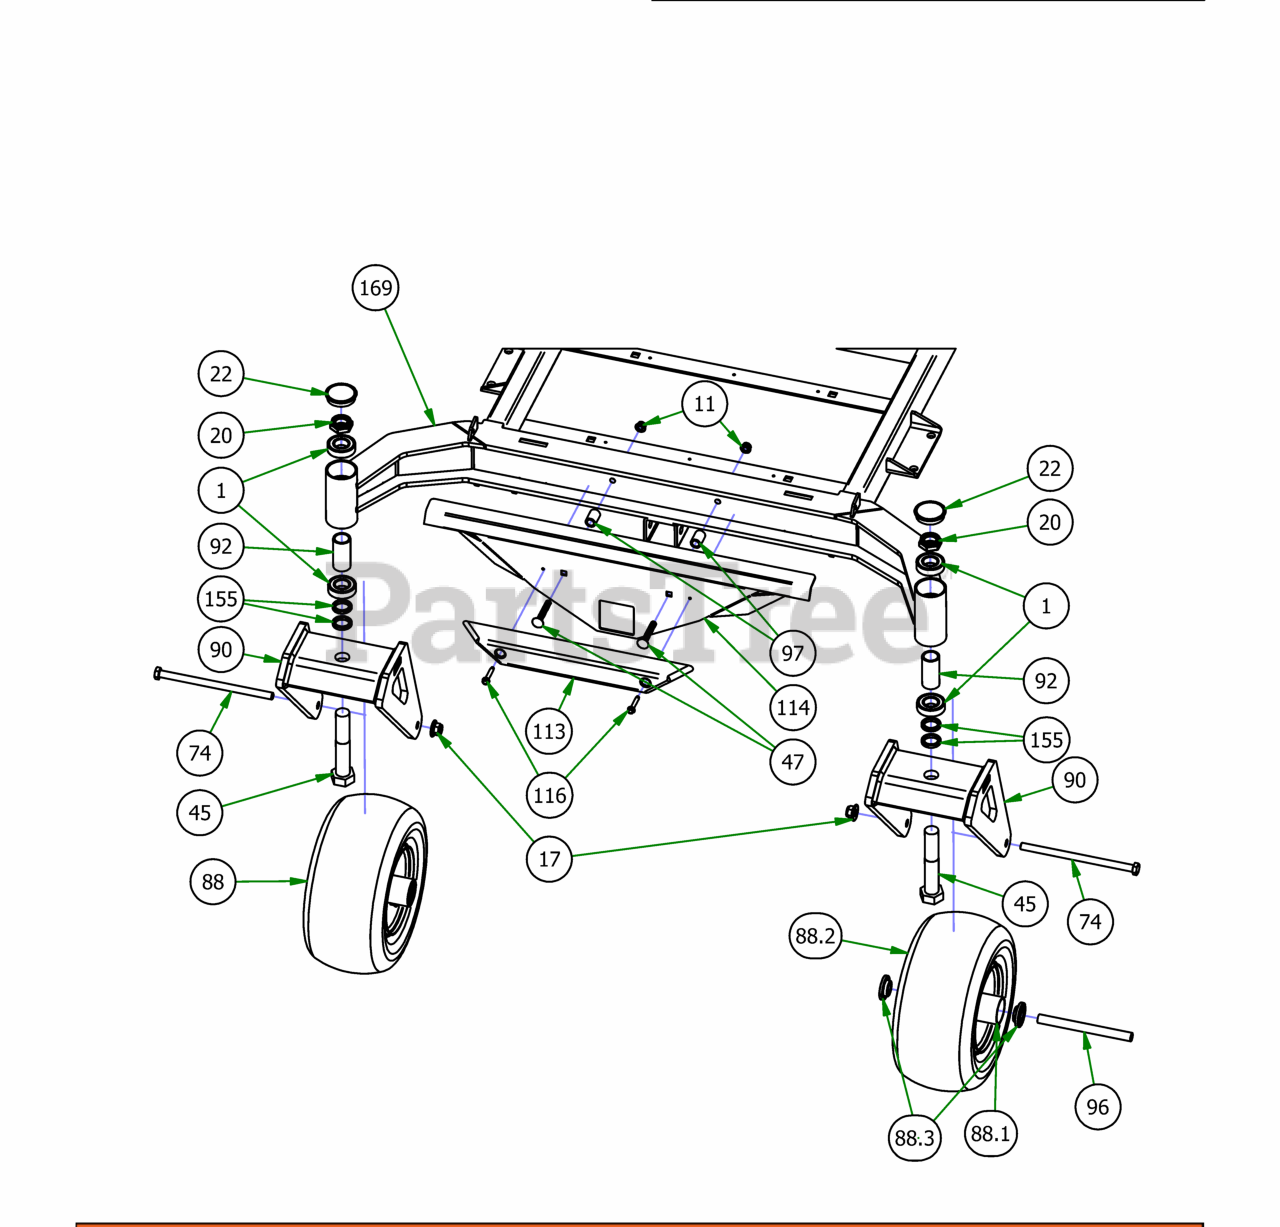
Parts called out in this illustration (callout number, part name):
1	1641 BEARING W/2 CONTACT RUBBER SEALS
11	3/8" Nylock Flange Nut
17	1/2-13 NYLON INSERT FLANGE LOCKNUT ZINC
20	1" Fine Thread 1/2 Nylock Nut
22	2017 Bearing Cover
45	1-14 x 5.5 Hex Bolt Grade 8 Zinc Yellow
47	3/8" x 2 1/2" Carriage Bolt
74	1/2" x 9" GR 5 Hex Bolt
88	Tire and black wheel assembly
88.1	Black Front Tire Rim
88.2	13 x 6.50 - 6 Tire
88.3	1-3/4" Bearing-Large Bore Front Rim
90	2019 Rebel Front Fork - Weldment
92	2016 Front Bearing Spacer
96	Front Wheel Spanner
113	2017 XP Bumper
114	2019 Outlaw Rigid Front Bumper Plate
116	1/4" x 1 1/2" Self Tapping Screw
155	Spacer, 1x1.375x.25
169	2019 Rebel Frame - Powdercoated
